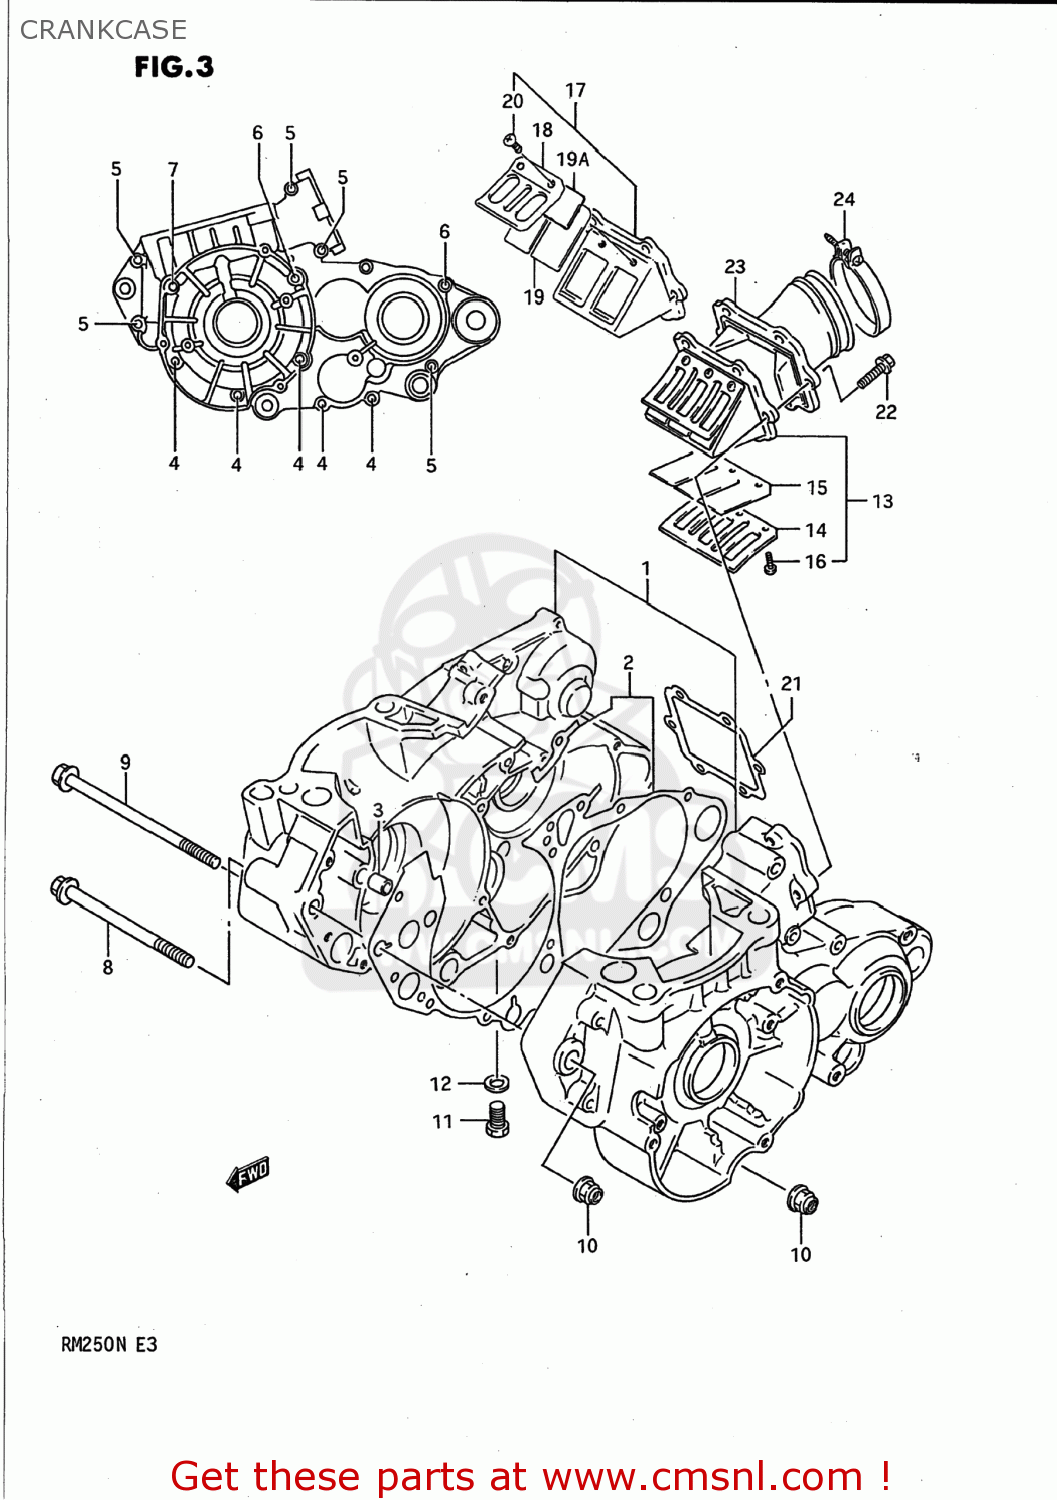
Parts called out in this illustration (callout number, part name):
1	CRANKCASE SET
2	GASKET,CRANKCASE (NAS)
3	PIN
4	BOLT
5	BOLT
6	BOLT
7	BOLT
8	BOLT
9	BOLT
10	NUT
11	NUT
12	GASKET 8.2X14X1 (NAS)
13	VALVE ASSEMBLY,REED
14	STOPPER,REED VALVE
15	VALVE,REED
16	SCREW
17	VALVE ASSEMBLY,REED
18	STOPPER,REED VALVE
19	VALVE,REED
19A	VALVE,REED UPR
20	SCREW
21	GASKET,REED VALVE (NAS)
22	BOLT
23	PIPE,INTAKE
24	CLAMP
